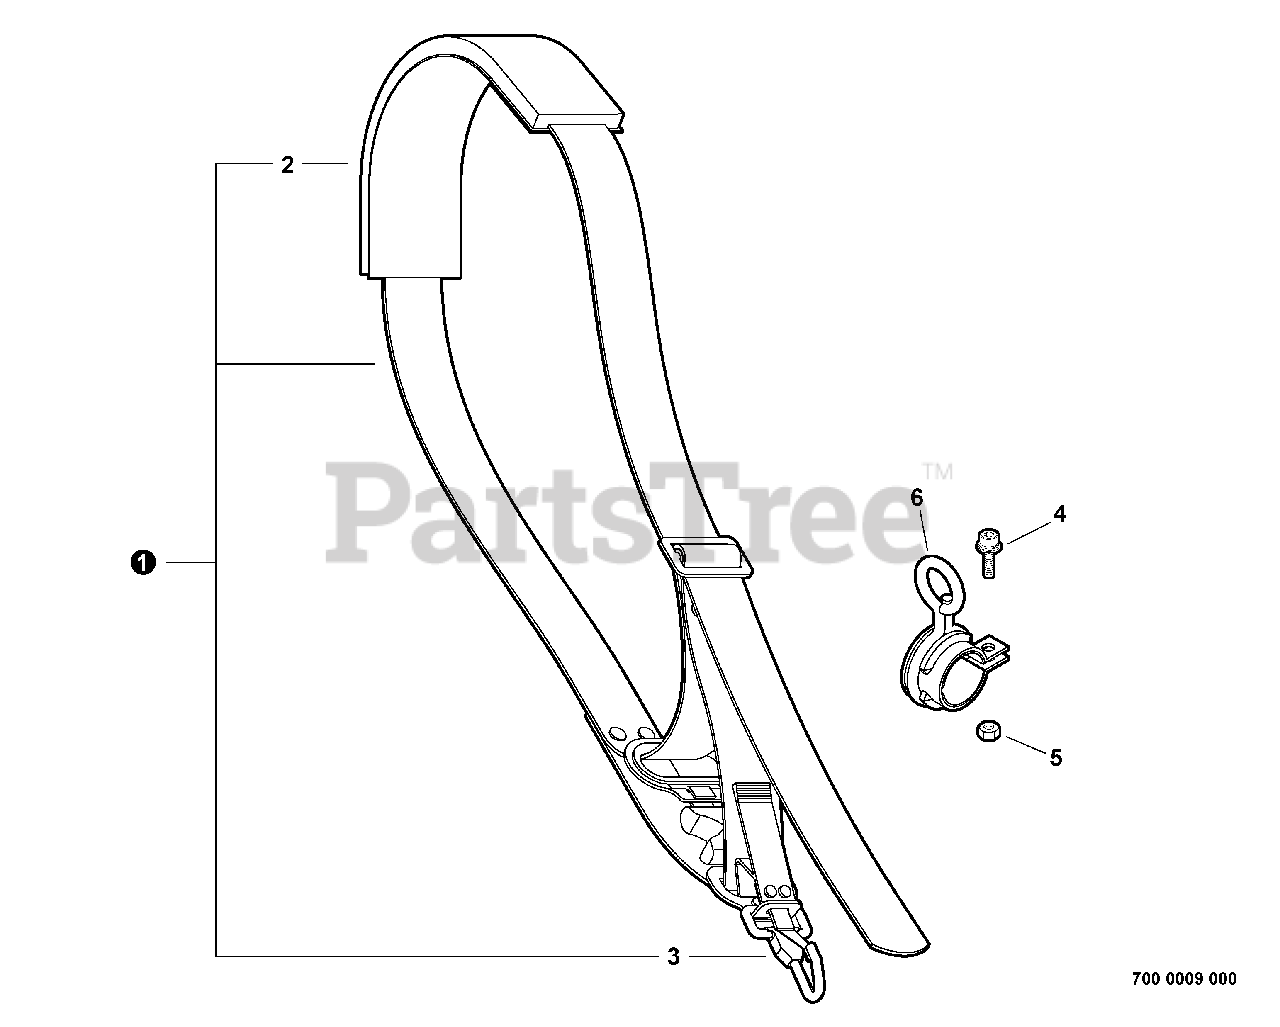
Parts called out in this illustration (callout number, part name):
1	SHOULDER STRAP ASSY
2	PAD, SHOULDER
4	SCREW - 5X12
6	HANGER ASSY
